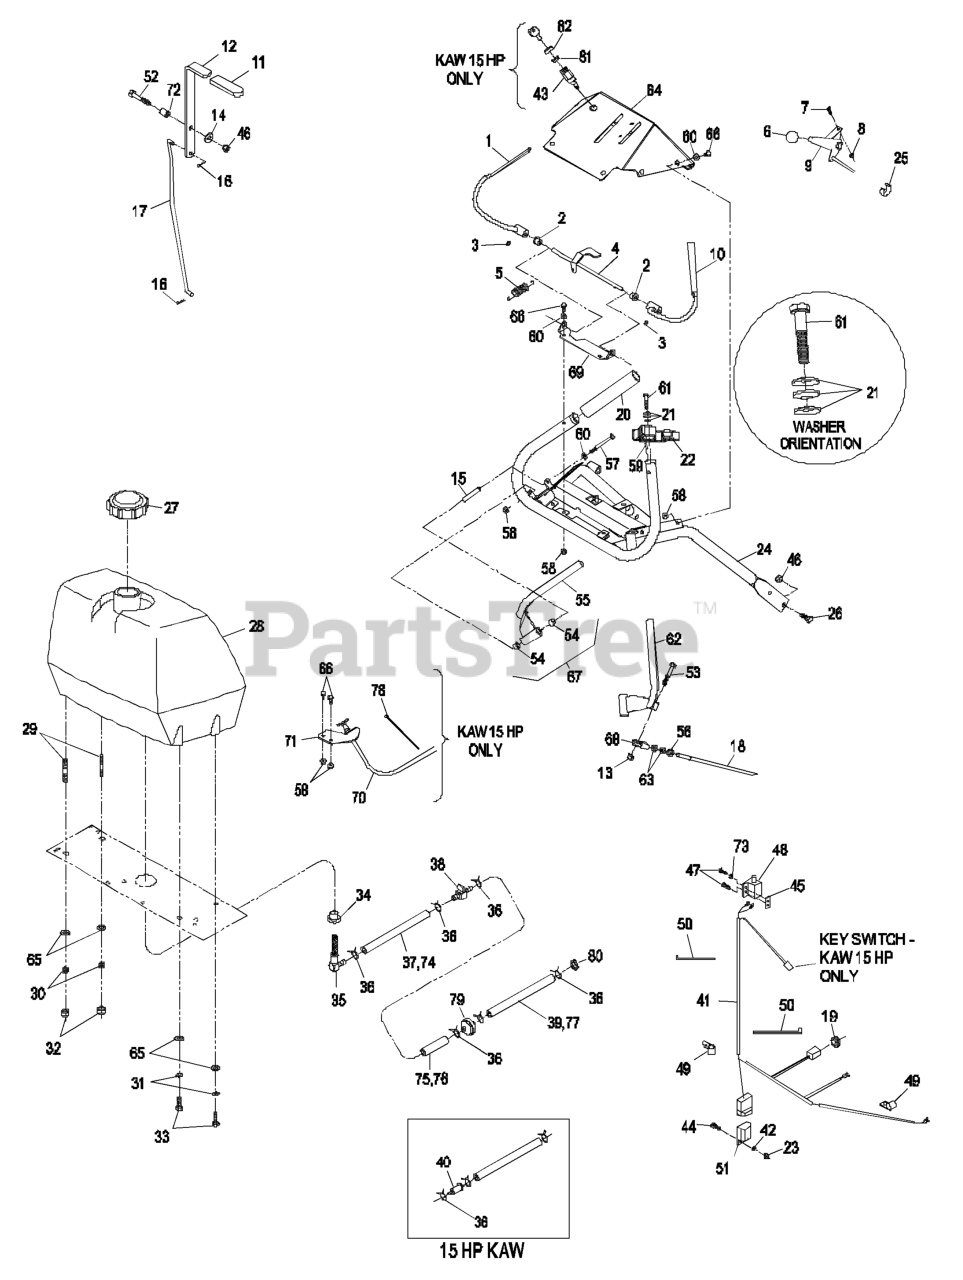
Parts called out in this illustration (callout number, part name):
2	BUSHING-NYLON
3	SCREW-SET
4	WLD,OPC LEVER AXLE
5	SPRING-EXTENSION
6	KNOB-BALL
7	BOLT-CARR
8	NUT-LOCK, NI
9	THROTTLE CABLE ASM
11	GRIP-LEVER
12	CLUTCH LEVER-W/GRIP
13	NUT-LOCK, NI
14	WASHER-FLAT
15	BUSHING-LEVER, DRIVE
16	PIN-COTTER
17	LINKAGE,UPPER BLADE (PLT)
18	LINKAGE,DRIVE (PLT)
19	GROMMET
20	GRIP-BAR, HANDLE
21	WASHER-SPRING
22	ASM,LH THUMB LATCH
23	NUT-LOCK, NI
24	WLD,UPPER ECS HANDLE
25	CLIP-CABLE
26	SCREW-HH
27	CAP-FUEL
29	STUD
30	SPRING-TANK, FUEL
31	WASHER-LOCK
32	NUT-LOCK, NI
33	SCREW-HH
35	ELBOW-TANK, FUEL
37	HOSE-FUEL
38	VALVE-FUEL
39	HOSE-FUEL
40	Kawasaki P/N 41019-1055 W/6" Fuel Line
41	HARNESS-WIRING
42	WASHER-FLAT
43	SWITCH & KEY (INCLUDES NU
44	SCREW-HH
45	PLATE-TAPPED
46	NUT-LOCK, NI
47	SCREW-PPH
48	SWITCH-OPEN, NORMALLY
49	CLIP-LOOM
50	TIE-CABLE
51	MODULE-INTERLOCK
52	SCREW-CARR
53	SCREW-HH
54	BUSHING-SLEEVE
56	NUT-HEX
57	SCREW-HH
60	WASHER-FLAT
61	SCREW-HH
63	NUT-HJ
65	WASHER-PLAIN
66	SCREW-HH
67	DRIVE LEVER-ASM, RH
68	JOINT-BALL, END
69	BRACKET,OPC AXLE
70	CABLE-CHOKE
71	BRACKET-CABLE, CHOKE
72	BUSHING-LEVER, LIFT
73	WASHER-FLAT
74	HOSE-FUEL
75	HOSE-LINE, FUEL
76	HOSE-FUEL
77	HOSE-LINE, FUEL
78	TIE-PLASTIC
80	CLAMP-HOSE
81	NUT-SWITCH, IGNITION
82	SEAL-SWITCH, IGNITION
